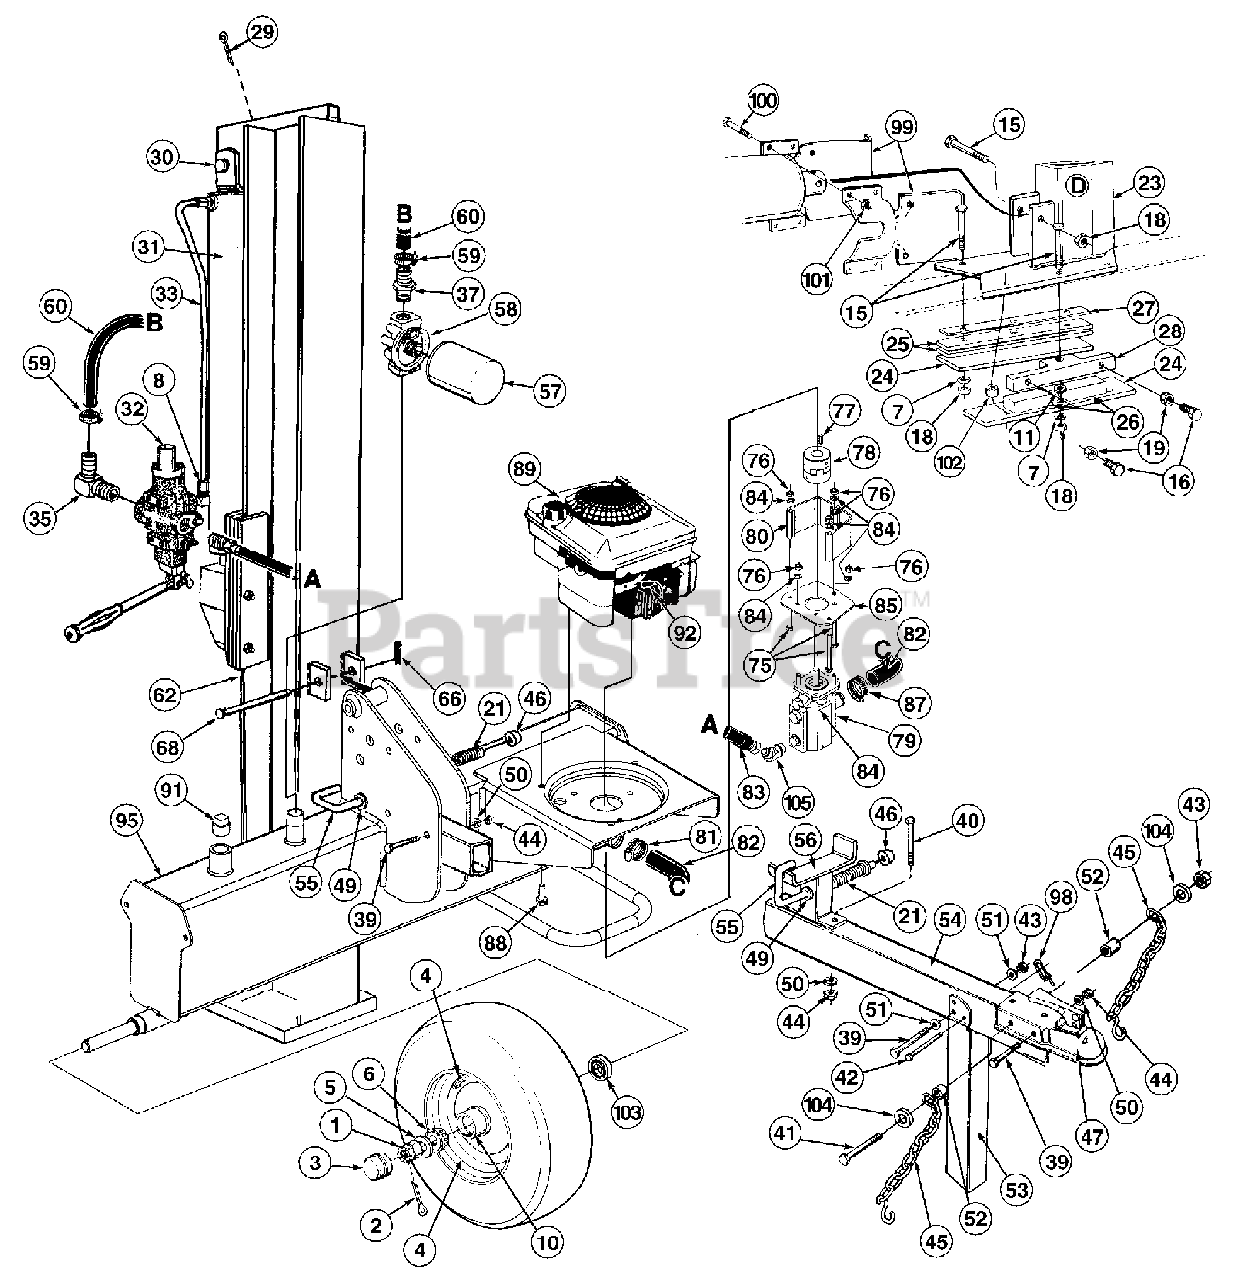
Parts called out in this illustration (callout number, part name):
1	Slotted Nut 3/4-16 Thd.
2	Cotter Pin 5/32" Dia. x 1-1/4" Lg.
3	Hub Cap
5	Fl-Wash. .76" I.D. x 1.5" O.D.
6	Bearing Cone
7	L-Wash. 1/2" I.D.
8	90° Solid Male Adapter
10	Bearing Cup
11	Fl-Wash. .531" I.D. x .94" O.D.
15	Hex Bolt 1/2-20 x 2.75" Lg. (Grd 8)
16	Hex Bolt 3/8-24 x 1.5" Lg.
18	Hex L-Nut 1/2-20 Thd.
19	Hex Jam Nut 3/8-24 Thd. (Grd 5)
21	Comp. Spring 4" Lg.
29	External Cotter Pin
30	Cylinder Mounting Pin
33	Metal Pressure Tube
35	Return Elbow
37	3/4" Hose Barb.
39	Hex Bolt 3/8-16 x 3" Lg.
40	Hex Bolt 3/8-16 x 4" Lg.
41	Hex Bolt 3/8-16 x 4" Lg. (Grd 5)
42	Clevis Pin 5/16 x 2.5" Lg.
43	Hex L-Nut 3/8-16 Thd.
44	Hex Nut 3/8-16 Thd.
45	Chain-Tow Hitch
46	Push Cap
47	Hitch Coupler
49	Fl-Wash. .635" I.D. x .93" O.D.
50	L-Wash. 3/8" I.D.
51	Fl-Wash. .406" I.D. x .75" O.D.
52	Spacer 3/8" I.D. x .625" O.D.
55	Locking Rod
57	Filter Element
58	Filter Head
59	Hose Clamp 5/8"
60	Return Hose 3/4" I.D. x 44" Lg.
68	Hinge Pin 1/2 x 4.8" Lg.
75	Hex Bolt 5/16-24 x 3.25" Lg.
76	Hex Nut 5/16-24 Thd.
77	Sq.-Key 3/16" x .75"
78	Flexible Coupling
79	Gear Pump
80	Coupling Shield
81	Hose Clamp
82	Suction Hose
83	High Pressure Hydraulic Hose
84	L-Wash. 5/16" I.D.
87	Hose Clamp
88	Hex Wash Hd. TT-Tap Scr. 3/8-16 x 1" Lg.
89	Engine
91	L-Vent Pipe Plug
92	Spark Plug Boot
101	Hex L-Nut 3/8-16 Thd.
102	Spacer 1/2" I.D. x .68" Lg.
103	Bearing Seal Only
104	Fl-Wash. 3/8" I.D. x .87" O.D.
105	45 degree Elbow
